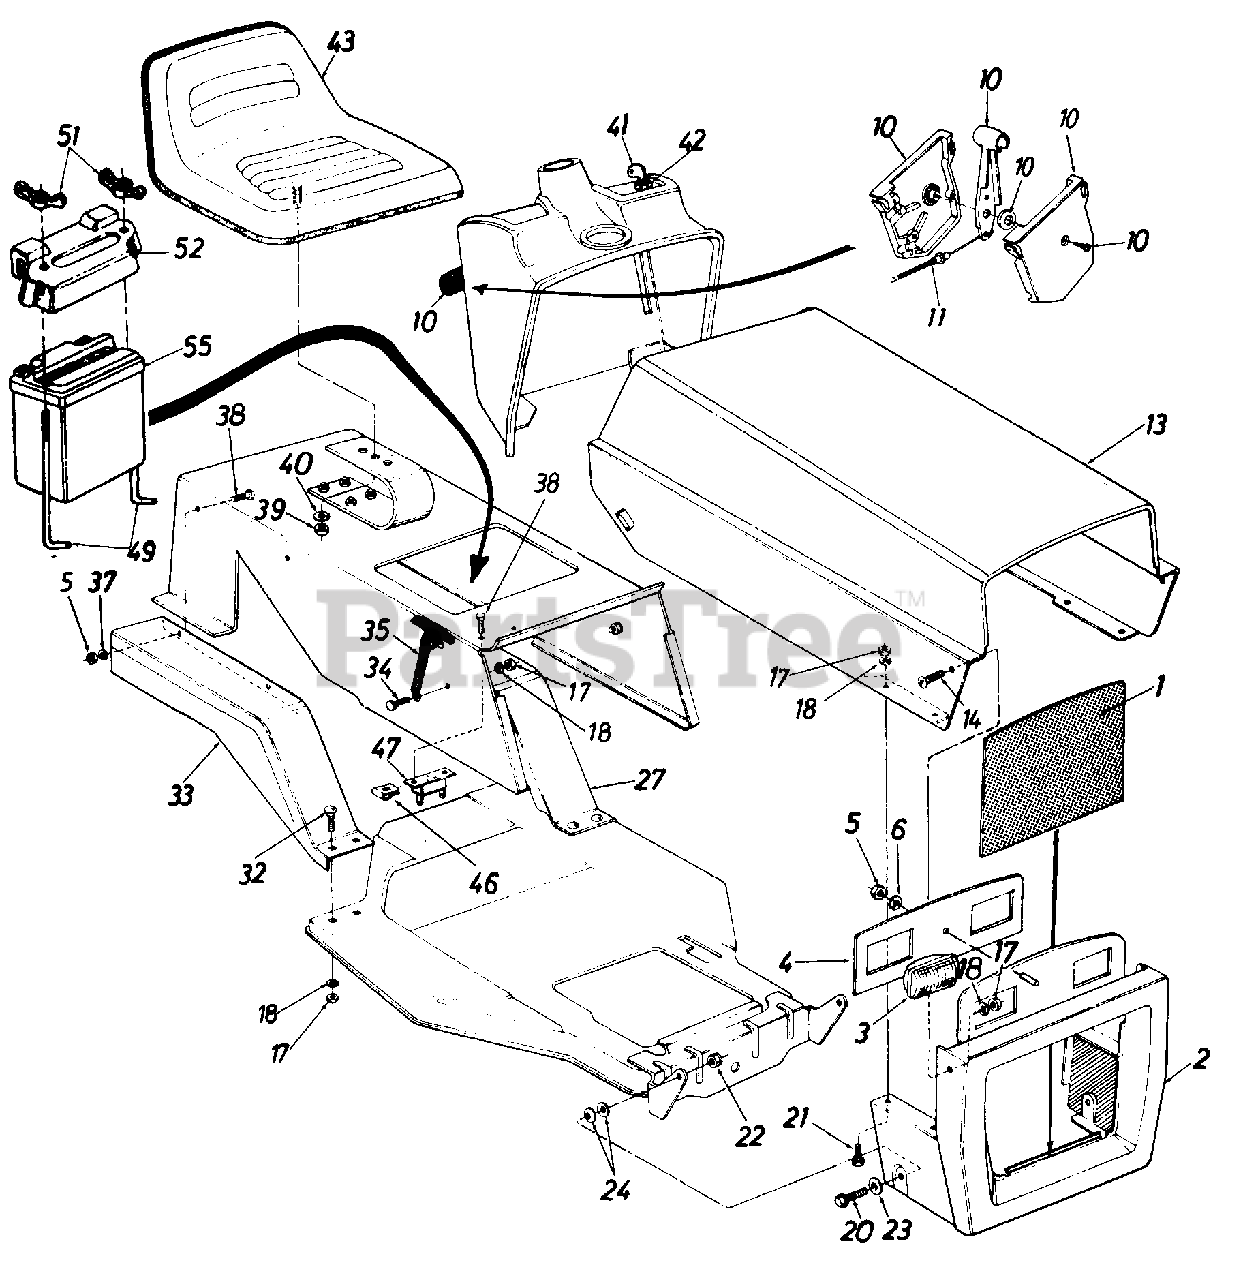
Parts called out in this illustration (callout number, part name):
1	Screen-Grille
2	Grille Ass'y.
3	Headlight
4	Headlight Retainer
5	Hex Nut #10-24 Thd.
6	L-Wash. #10 I.D.
10	Throttle Control Box Ass'y.
11	Throttle Control Wire
13	Hood-Front
14	Truss Hd. Mach. Scr. 1/4-20 x .50" Lg.*
17	Hex Nut 1/4-20 Thd.*
18	L-Wash. 1/4" I.D.*
20	Hex Bolt 3/8-16 x 1" Lg.*
21	Hex Sems Bolt 1/4-20 x .75"
22	Hex Cent. L-Nut 3/8-16 Thd.
23	Fl-Wash. .385" I.D. x .62" O.D.
24	Bell-Wash. .4" I.D. x .88"
27	Fender Ass'y. L.H.
32	Carriage Bolt 1/4-20 x .62"
33	Fender Ass'y. R.H.
34	Hex Bolt 1/4-20 x .62" Lg.
35	Hood Lock Ass'y.
37	Wash. #10 I.D.
38	Truss Hd. Mach. Scr. #10-24 x .62" Lg.*
39	Hex Nut 1/2-13 Thd.
40	L-Wash. 1/2" I.D.
41	Ignition Key
42	Ignition Switch
43	Seat Ass'y.
46	Speed Nut 10-24
47	Circuit Breaker
49	Hold-Down Rod
51	Wing Nut 1/4-20 Thd.
52	Battery Cover
55	12V Battery
